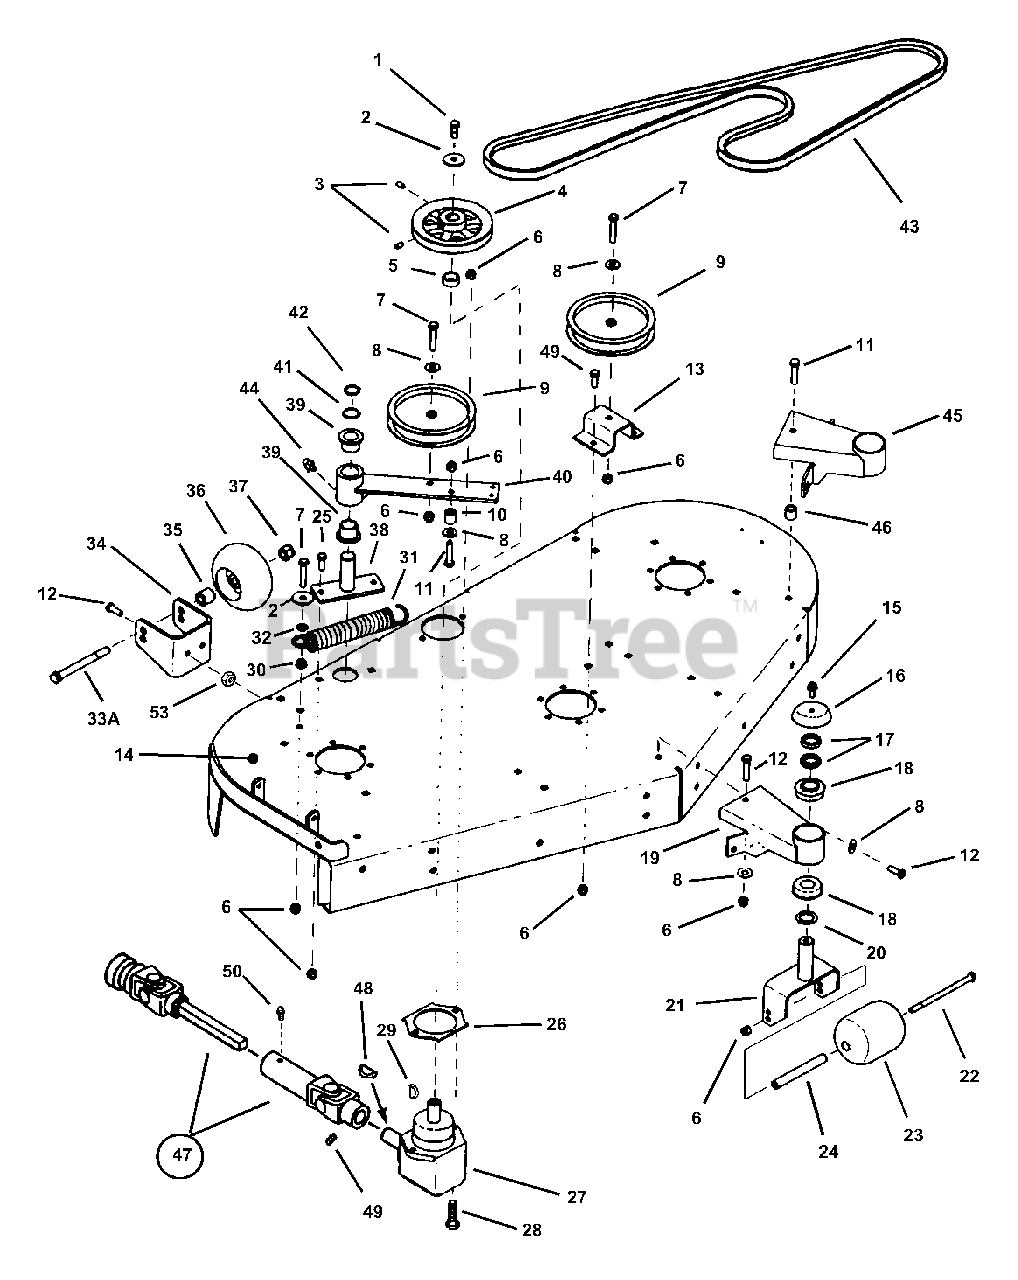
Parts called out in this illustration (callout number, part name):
1	BOLT, 3/8-24 X 1" GD8 YZ
2	WASHER, 13/32" Flat
3	SET-SCREW, 5/16" x 5/8" Socket Head
4	PULLEY, Cast 5-3/4" O.D.
5	SPACER
6	NUT, 3/8-16 HEX NYLON LOCK
7	BOLT, 3/8-16 X 2, GD5, CZ
8	WASHER, 3/8" USS
9	PULLEY, 5-1/2 Idler
10	SPACER, 3/4" Outside Diameter
11	SCREW, 3/8-16 x 1-3/4" Hex Head Cap Grade 5
12	BOLT, 3/8-16 X 1" GD5 CZ
13	STAND, Fixed Idler
14	WELDMENT, Deck, 52"
15	SCREW, 5/16-18 x 3/4" Hex Washer Self Tap
16	CAP, Caster Shaft
17	SPACER, 1" x 1 3/8 x .30" (PM)
18	BEARING, Radial Flanged
19	WELDMENT, Gauge Wheel Bracket
20	BUSHING, 1" Machine
21	WELDMENT, Gauge Wheel Caster
22	BOLT, 3/8-16 X 6" GD5 CZ
23	ROLLER, 3-3/4" x 4-13/16" Nylon
24	TUBE, Axle
25	BOLT, 3/8-16 x 1" Carriage, Grade 5
26	GEARBOX, Shim
27	GEARBOX, Right Angle (Peerless Series 1000-52)
28	BOLT, 3/8-16 X 1-1/4" GD5 CZ
29	KEY, #6 x 5/8" Woodruff
30	NUT, 3/8-16 HEX SERRATED FLANGE
31	SPRING, Extension
32	RETAINER, 3/8" Bolt
33A	BOLT, 1/2-13 X 5 GD5 YZ
34	FORK, Gauge Wheel
35	SPACER, Gauge Wheel
36	WHEEL, Gauge
37	NUT, 1/2-13 Hex Nylock
38	WELDMENT, Idler Pivot
39	BUSHING, Caster
40	WELDMENT, Idler Arm
41	WASHER, 1-1/32" Flat
42	RING, 1" External Retaining
43	BELT, 52" HB (122")
44	ZERK, 1/4-28 Self Tapping
45	WELDMENT, Gauge Wheel
46	SPACER, 3/8" Inside Dia.
47	DRIVESHAFT, Telescoping
48	KEY, #9 Woodruff
49	SET SCREW, 3/8-16 x 3/8" Hex Recess
50	FITTING, 1/4-28 Lube
53	NUT, 3/8-16 Hex Center Lock
